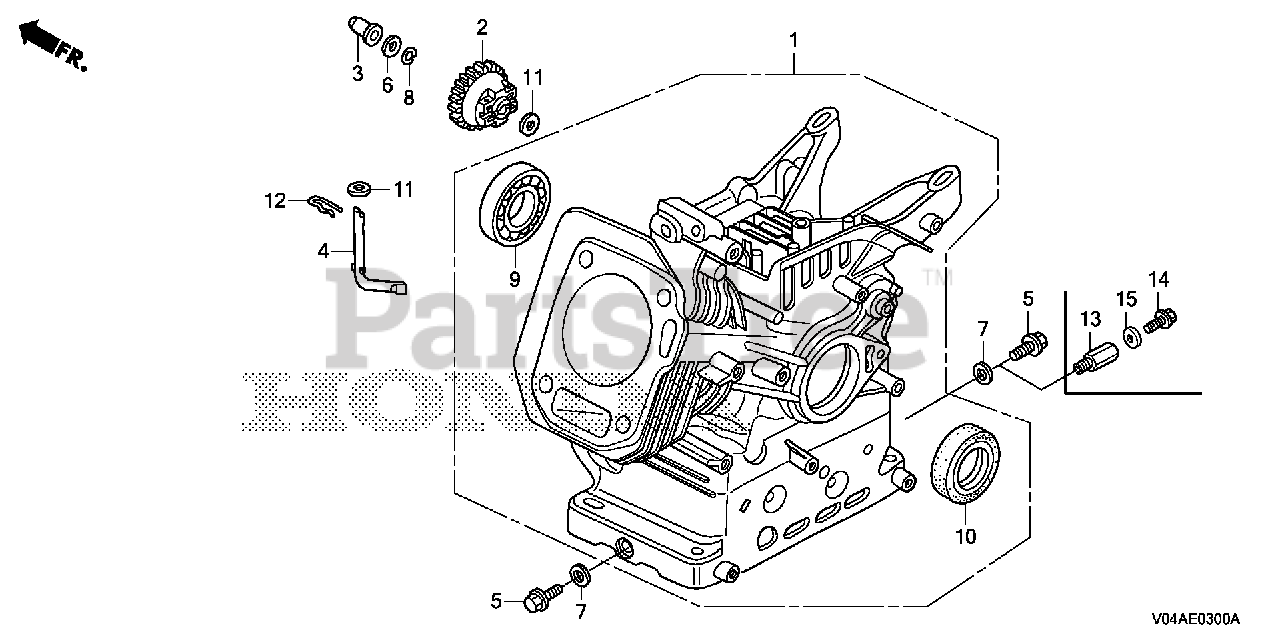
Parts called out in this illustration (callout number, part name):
1	CYLINDER ASSY.
2	GOVERNOR ASSY.
3	SLIDER, GOVERNOR
4	SHAFT, GOVERNOR ARM
5	BOLT, DRAIN PLUG
6	WASHER, THRUST (6MM)
7	WASHER, DRAIN PLUG (10.2MM)
8	CLIP, GOVERNOR HOLDER
9	BEARING, RADIAL BALL (6205TMB) (NTN)
9	BEARING, RADIAL BALL (6205) (NSK)
10	OIL SEAL (25X41X6) (NOK)
10	OIL SEAL (25X41X6) (ARAI) (NOT AVAILABLE)
11	WASHER, PLAIN (6MM)
12	PIN, LOCK (8MM)
13	EXTENSION, OIL DRAIN
14	BOLT, SPECIAL (8MM) (SOURCE: VINTAGE PARTS INC.)
15	GASKET (8MM)
